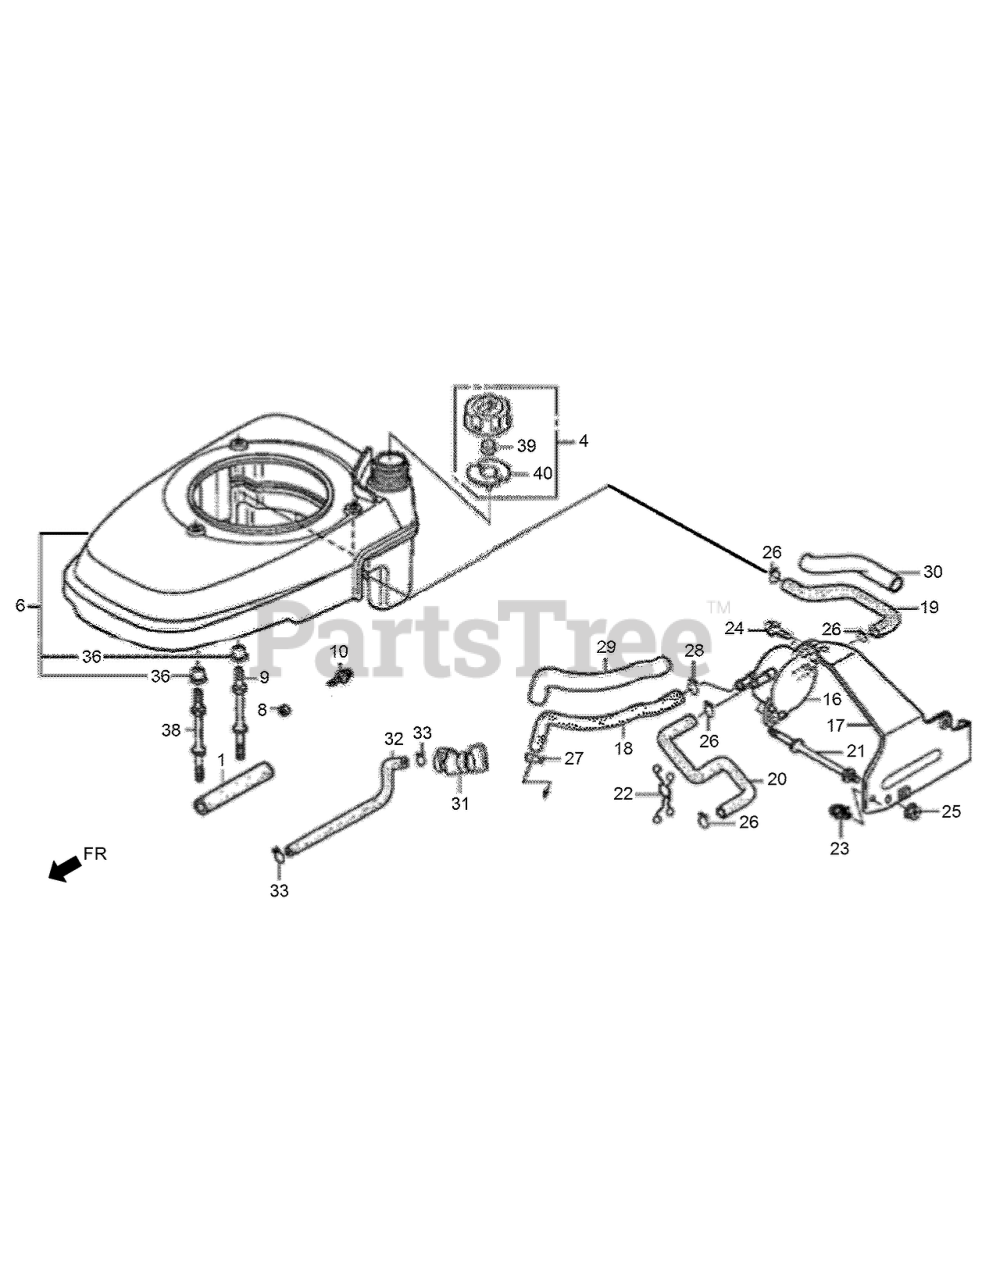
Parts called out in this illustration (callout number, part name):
1	RUBBER-SUPPORTER
4	CAP ASM-FUEL TANK
6	FAN COVER ASM (NH1)
8	COLLAR-FR WINKER
9	BOLT-STUD
10	SCREW-WASHER-5X10
16	PUMP ASM-FUEL
17	STAY-FUEL PUMP
18	TUBE-DIAPHRAGM
19	TUBE-FUEL TANK
20	TUBE B-FUEL
21	BOLT-STUD
22	CLIP-PURSE LOCK
23	CLIP-WIRE HARNESS
24	SCREW-WASHER-5X14
25	NUT-FLANGE-6MM
26	CLIP-TUBE
27	CLIP-TUBE
28	CLIP-TUBE
29	TUBE-VINYL-9X11X210
30	TUBE-VINYL-11X13X100
31	COCK ASM-FUEL
32	TUBE-FUEL
33	CLIP-TUBE
36	COLLAR-FAN COVER
38	BOLT-STUD
39	SPONGE-FUEL CAP BREATHER
40	PACKING-FUEL CAP
